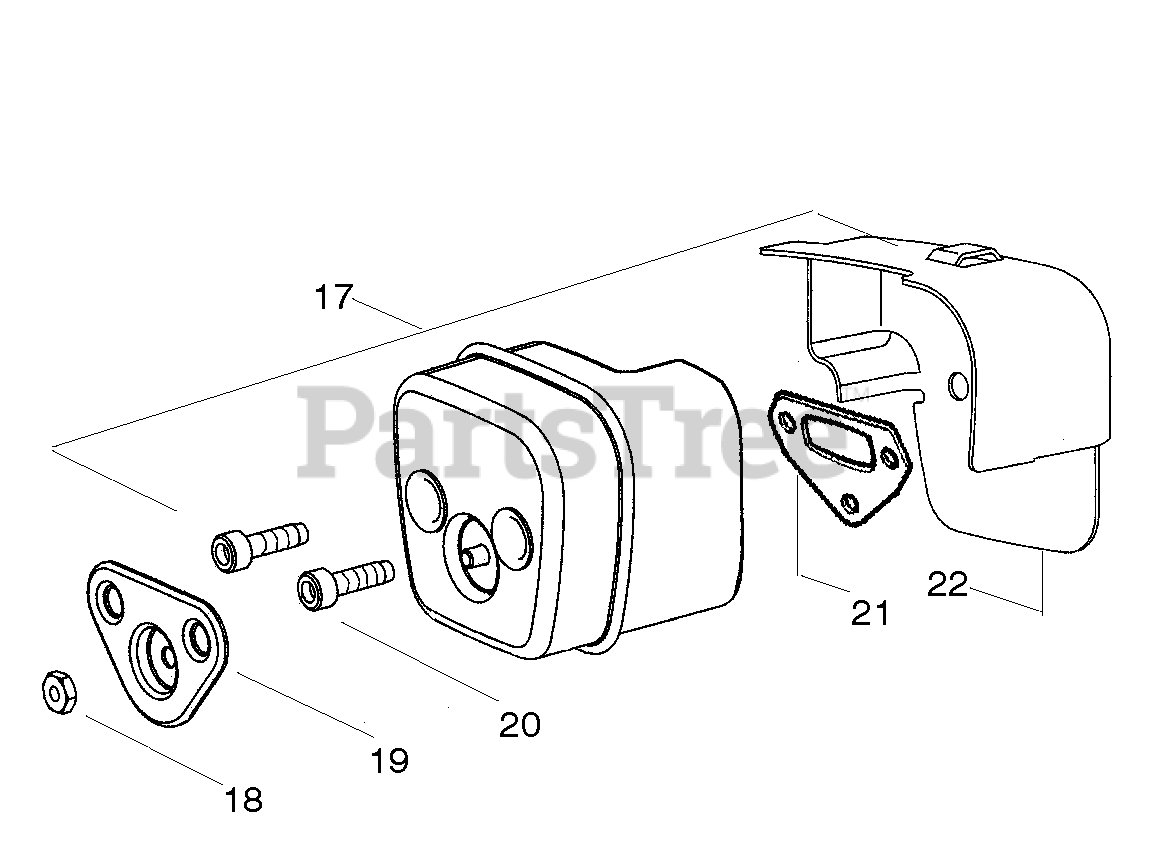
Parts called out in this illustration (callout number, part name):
17	Kit-Muffler
18	Nut-Brass
19	Cover-Bolt
20	Bolt-Muffler
21	Gasket-Muffler
22	Backplate-Muffler
